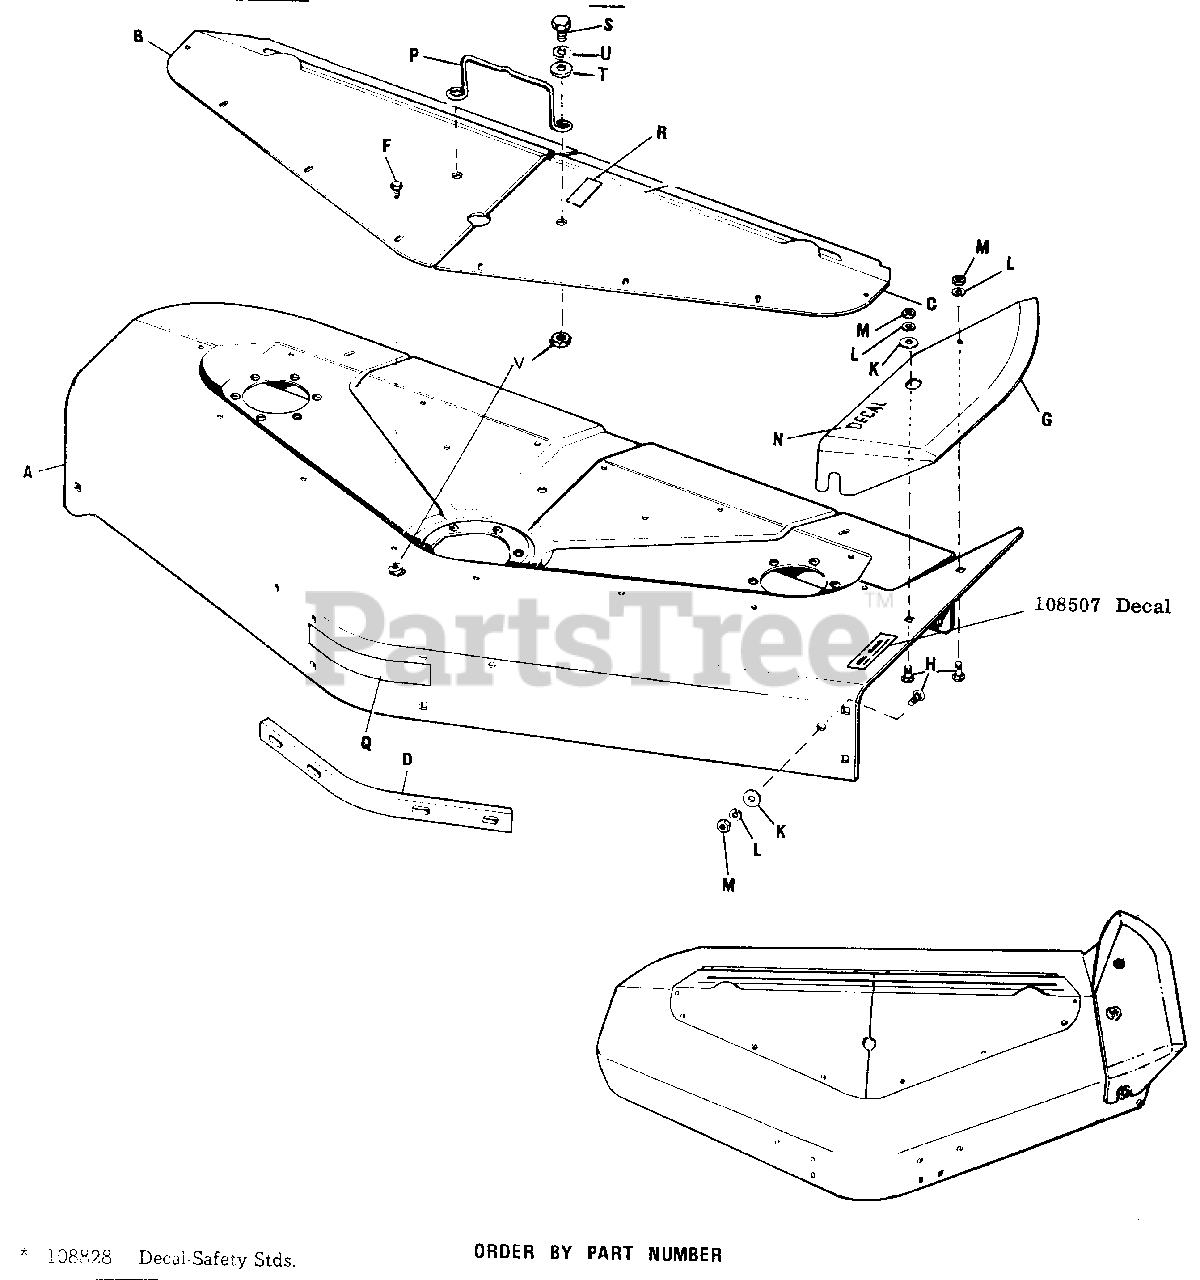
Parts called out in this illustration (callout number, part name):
A	Mower Housing
B	R.H. Cover
C	L.H. Cover
D	Reinforcing Bar
F	Self Tapping Screw, 1/4"-20 x 3/8"
G	Deflector
H	Carriage Bolt, 3/8"-16 x 3/4"
K	Special Washer
L	Lock Washer, 3/8"
M	Hex. Nut, 3/8"-16
P	Guide Belt
Q	Film Simplicity
R	Film-Belt Instructions
S	Hex. Cap Screw, 5/16"-18 x 3/4"
T	Plain Washer, 5/16"
U	Lock Washer, 5/16"
V	Nut Retainer, 5/16"
